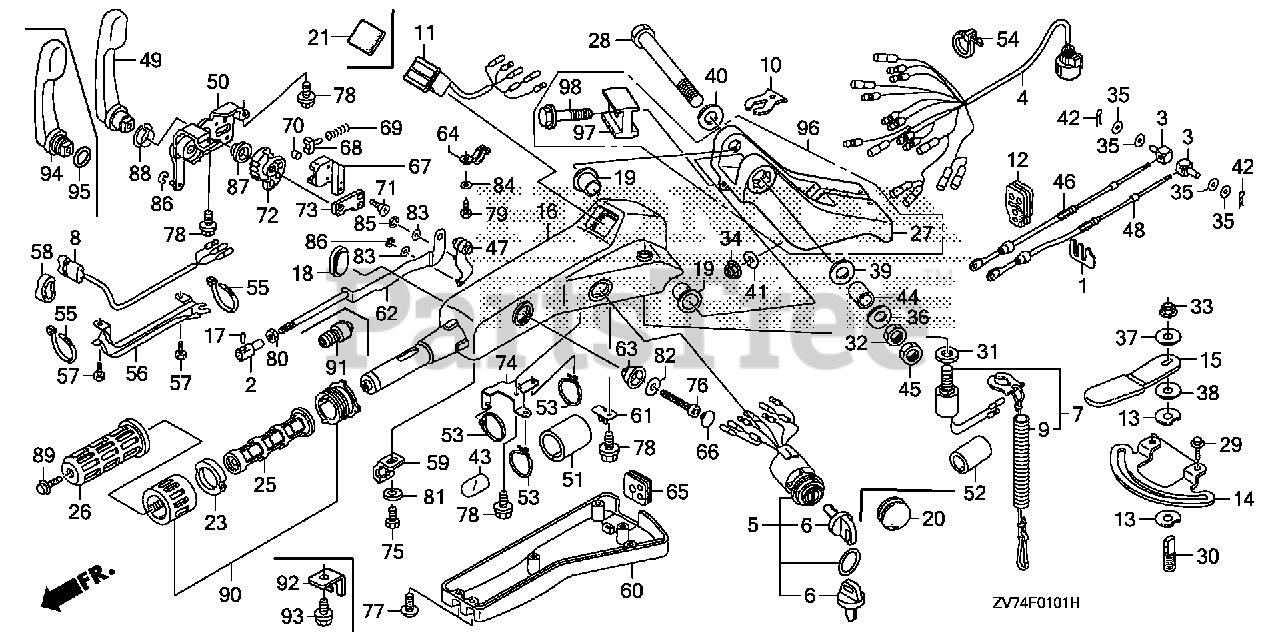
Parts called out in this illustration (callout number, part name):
1	PLATE, REMOTE CONTROL CABLE
2	PIVOT, THROTTLE CABLE
3	PIVOT, SHIFT
7	SWITCH ASSY., EMERGENCY STOP
9	WIRE, EMERGENCY
10	CLIP, EMERGENCY LOCK
12	GROMMET, CASE (LOWER) (A)
16	HOUSING *NH282MU* (OYSTER SILVER METALLIC-U)
17	PIN, THROTTLE CABLE
18	GROMMET, POWER TILT SWITCH
19	BUSH, HANDLEBAR
20	GROMMET, COMBINATION SWITCH
21	GROMMET, LAMP INDICATOR
22	GRIP ASSY., THROTTLE FRICTION
23	PAD, THROTTLE FRICTION
24	BLOCK, THROTTLE FRICTION
25	PIPE, GRIP
26	RUBBER, GRIP
27	BRACKET, STEERING *NH282MU* (OYSTER SILVER METALLIC-U)
28	BOLT, HEX. (12X80)
31	NUT, HEX. (16MM)
32	NUT, HEX. (12MM)
34	NUT, SELF-LOCK (10MM)
35	WASHER, PLAIN (6MM)
36	WASHER, WAVE (14MM)
39	WASHER, PLAIN (12MM)
40	WASHER, PLAIN (12MM)
41	WASHER, PLAIN (10MM)
42	PIN, SPECIAL LOCK (6MM)
44	COLLAR, DISTANCE (12.2X23X16)
45	NUT, HEX. (12MM)
46	CABLE, THROTTLE
47	ARM, THROTTLE
48	CABLE, SHIFT
49	LEVER, SHIFT
50	FRAME ASSY., SHIFT
53	BAND (CONVEX CV-150)
59	HOLDER, SWITCH
60	COVER, HANDLEBAR (LOWER)
61	BRACKET, CABLE
62	PLATE ASSY., LOCK
64	PLATE, GUIDE
67	GUIDE, SPRING
69	SPRING, COIL
71	SCREW (M5X14)
72	GEAR, SHIFT
73	PLATE, BALL GUIDE
75	BOLT (M5X8)
76	BOLT (M8X50)
77	BOLT (M5X12)
78	BOLT (M6X12)
79	BOLT (M5X12)
80	NUT, HEX. (5MM)
81	WASHER (5MM)
82	WASHER (8MM)
83	WASHER (10MM)
84	WASHER (5MM)
89	BOLT, FLANGE (6X12)
90	GRIP ASSY., THROTTLE FRICTION
96	BRACKET KIT, STEERING *NH282MU* (OYSTER SILVER METALLIC-U)
97	BLOCK, HEIGHT ADJUSTER
98	BOLT, FLANGE (8X28)
